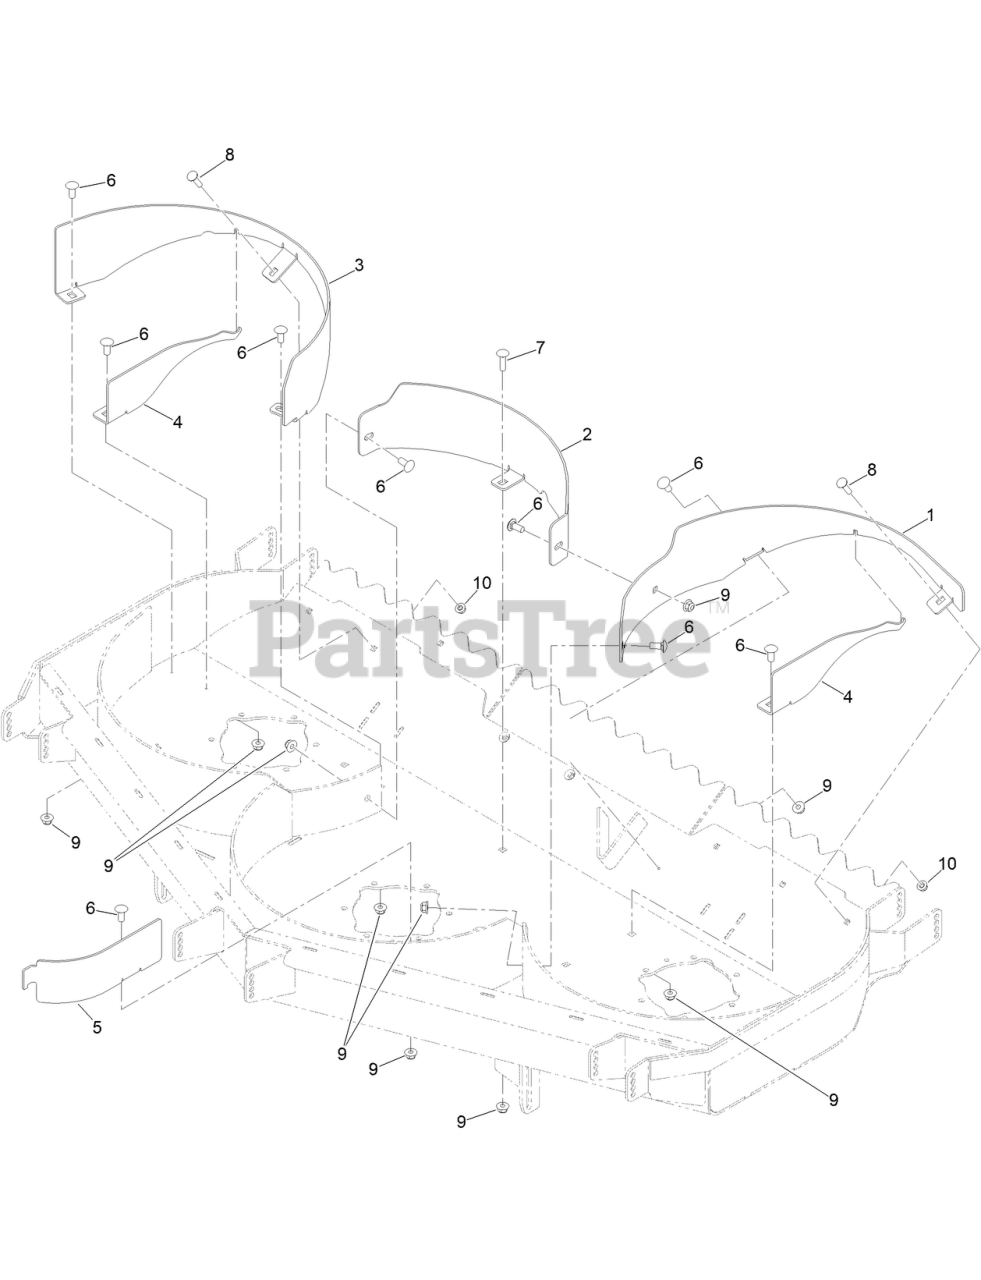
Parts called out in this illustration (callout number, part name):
1	BAFFLE-RECYCLER, RH
2	BAFFLE-RECYCLER, CENTER
3	BAFFLE-RECYCLER, LH
4	BAFFLE-KICKER, SIDE
5	BAFFLE-KICKER, CENTER 60RD
6	SCREW-CARR
7	SCREW-CARR
8	SCREW-CARR
9	NUT-HF, NI
10	NUT-HF, NI
